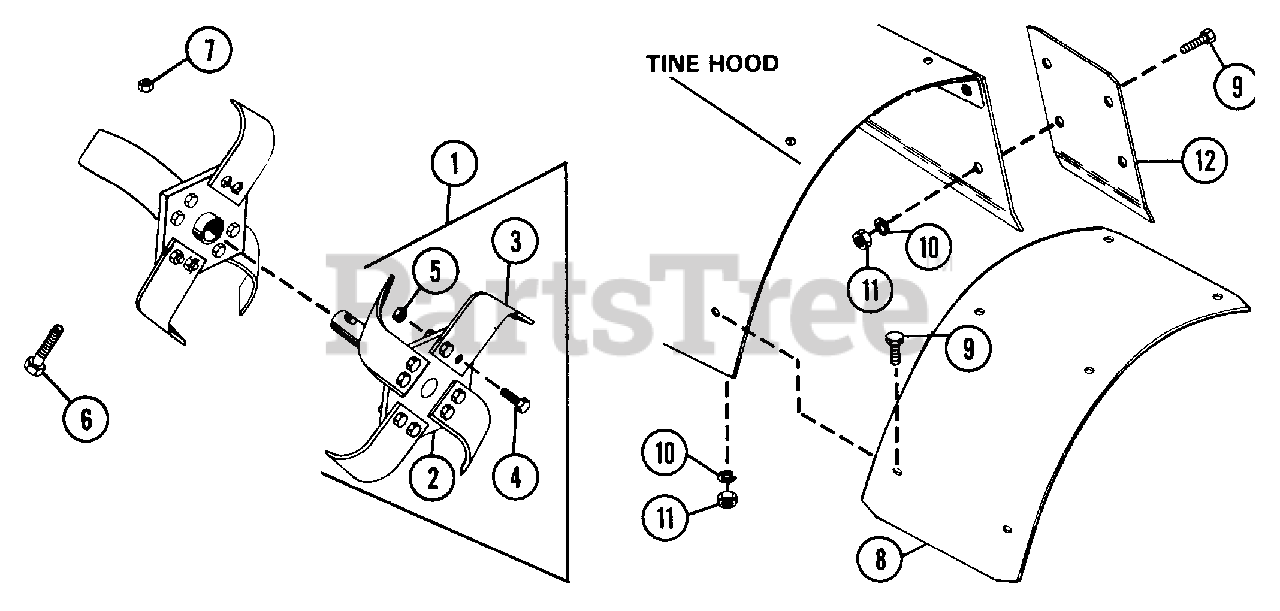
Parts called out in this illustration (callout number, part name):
2	OUTER TINE HUB
3	L KNIFE TINE
4	BLT-HEX .44-14X1.00 GR5
5	NUT-LK-TOP .437-14 GR C PL
6	BLT-HEX .38-16X2.00 GR8
7	NUT-LK TOP .375-16 GR C YWZC
8	TINE HOOD EXTENSION
9	BLT-HEX .25-20X.50 PL GR2
10	WSHR-LK .250X.077 HVY PL
11	NUT-HEX .250-20 PL
12	TAILBOARD EXTENSION
